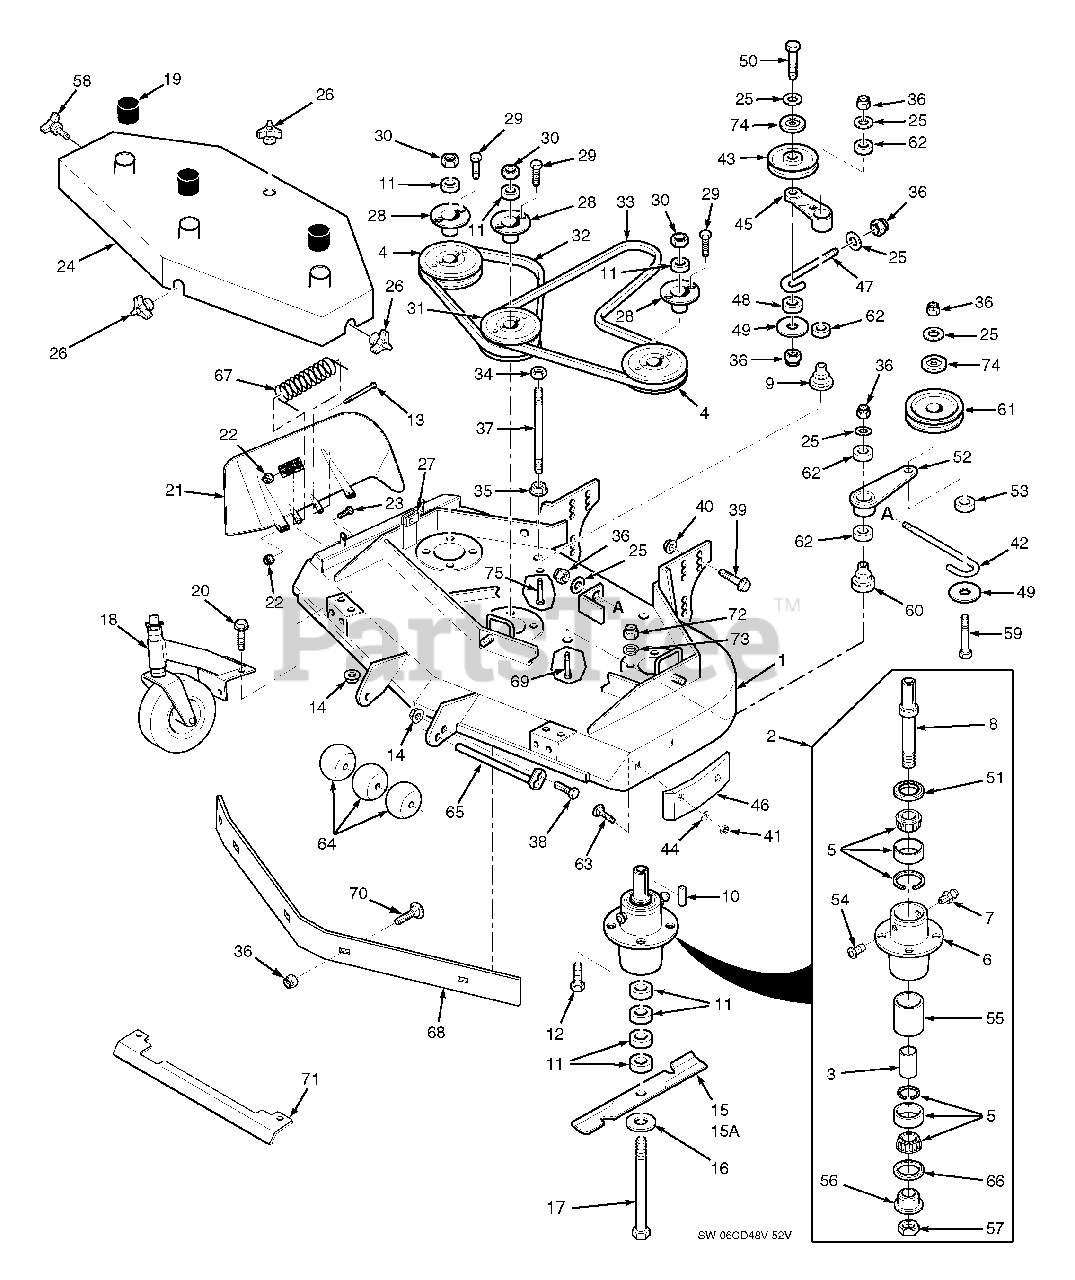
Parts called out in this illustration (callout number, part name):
1	Cutter Deck
2	Spindle Assembly
3	Spacer, Inside
4	Pulley
5	Tapered Bearing (Two)
6	Spindle Housing
7	Grease Fitting Str. 5/16"
8	Spindle Shaft, Tapered Brng
9	Idler Pivot
10	Key, 1/4 x 1/4 x 2"
11	Spacer, Cutter Blade - Small
12	Bolt, 5/16-18 x 1-1/2" Hex Head GR-8
13	Bolt, 5/16-18 x 4-3/4" Hex Head
14	Serrated Flange Nut, 5/16-18
15	Cutter Blade 16-1/2" Marbain
15	Cutter Blade 18" Marbain
15A	Cutter Blade 16-1/2 High Lift Marbain
15A	Cutter Blade 18 High Lift Marbain
16	Flatwasher,5/8" (.688 x 1.75 x .134)
17	Hex Head Bolt, 5/8-11 x 9-1/2"
18	Caster Assembly
19	Spindle Shield
20	Capscrew, 5/16-18 x 3/4"
21	Discharge Chute 48V
22	Nut, 5/16-18 Elastic Elastic Stop
23	Bolt, 5/16-18 x 1-1/2" Hex Head
24	Belt Cover
25	Flat Washer, 3/8" Special
26	Wing Nut, 3/8-16 (Large)
27	U-Nut, 3/8-16
28	Tapered Hub
29	Bolt, 1/4-20 x 1" Hex Head Grade 8
30	Nut, 5/8-11 Hex
31	Pulley, Double
32	Belt, RH Blade Drive
33	Belt, Blade Drive
34	Nut, 3/8-16, Nut Centerlock
35	Nut, 3/8-16, Serrated Flange
36	Nut, 3/8-16 Elastic Stop
37	Support, Belt Cover
38	Bolt, 5/16-18 x 1" Hex Head
39	Cpscrw, 1/2-13 x 1" Ser.Flg. HH
40	Nut, 1/2-13 Spiralock
41	Hex Nut, 5/16-18 Center Locknut
42	J-Hook, 48V
43	Idler Pulley, "V" Groove
44	Flatwasher, 5/16"
45	Idler Arm Assy.
46	Pad, Deck Wear
47	J-Rod, Idler Pulley
48	Spacer, J-Rod
49	Washer, 3/8 x 1-1/2 x 16 ga.
50	Bolt, 3/8-16 x 2-1/2" Hex Head
51	Seal, Cutter Spindle
52	Idler Arm Assy
53	Spacer, J-Rod
54	Reief Fitting, Cutter Spindle
55	Spacer, Outside, Cutter Spindle
56	Spindle Bushing
57	Nut, Cutter Spindle
58	Knob, w/stud
59	Bolt, 3/8-16 x 3-3/4" Hex Head
60	Idler Pivot
61	Idler Pulley, Belt Clutch
62	Bearing
63	Bolt, Carriage 5/16-18 x 3/4"
64	Guide Roller
65	Roller Shaft
66	Seal, Cutter Spindle
67	Spring, Chute Return
68	Baffle Weldment 48V
69	Bolt, 3/8-16 x 3-1/4" Hex Head
70	Bolt, Carriage 3/8-16 x 1"
71	Heatshield
72	Nut, Hex Lock 5/16-18
73	Lock Washer 5/16
74	Dust Shield
75	Bolt, 3/8-16 x 2-3/4" Hex Head
